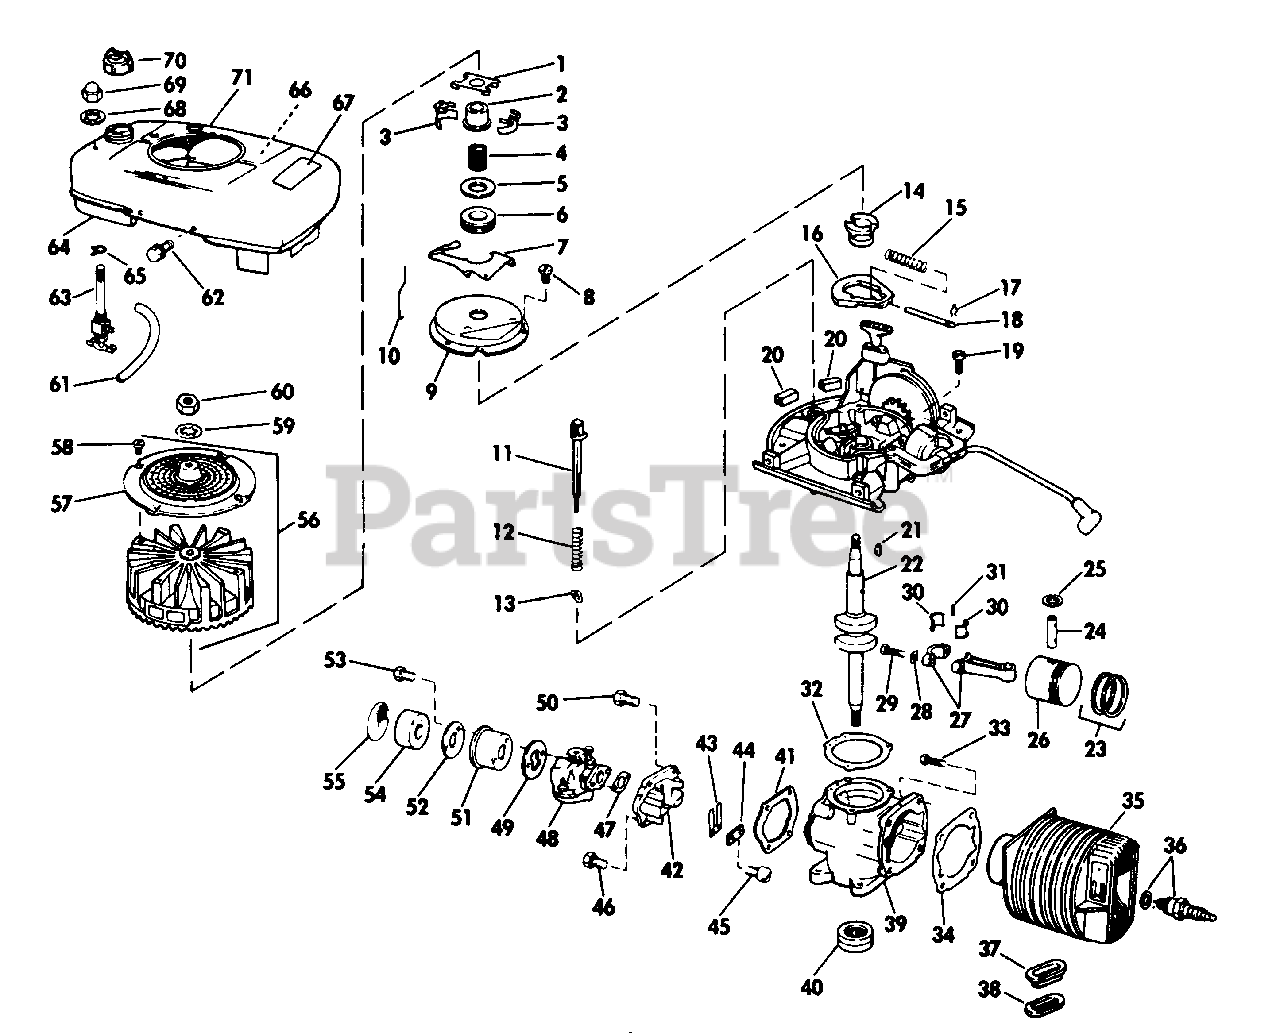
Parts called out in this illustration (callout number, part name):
1	Yoke-Governor
2	Collar-Governor
3	Weight-Governor
4	Spring-Governor
5	Thrust Washer
6	Collar-Thrust
7	Lever-Governor
8	Screw-Attaching Dust Cover
9	Dust Cover
10	Rod-Governor
11	Bar-Shut-Off and Primer
12	Spring-Shut-Off Switch
13	Blade-Switch
14	Cam-Spark Advance
15	Spring-Spark Advance
16	Flyweight-Spark Advance
17	Retainer-Spring
18	Pin-Spark Advance
19	Screw-Arm. Plate to Crankcase
20	Pad-Rubber. Arm. Plate
21	Key-Crankshaft
22	Crankshaft
23	Ring Set (2 Rings)
24	Wrist Pin
25	Retaining Ring-Wrist Pin
27	Connecting Rod Assy.
28	Lockplate
30	Liners-Connecting Rod
31	Needle Set
32	Gasket-Crkc. to Arm. Pl. .005 in.
32	Gasket-Crkc. to Arm. Pl. .010 in.
33	Screw-Machine, Cyl. to Crkc.
34	Gasket-Cyl. to Crankcase
35	Cylinder and Sleeve Assy.
36	Spark Plug and Gasket
37	Sleeve-Exhaust Gasket
38	Gasket-Exhaust
39	Crankcase and Seal Assy.
40	Oil Seal
41	Gasket-Reed Plate
42	Reed Plate Assembly
44	Plate-Back-Up
45	Machine
46	Scr.-Reed Pl. to Crkc.
47	Gasket-Carburetor
48	Carburetor Assembly
50	Scr.-Reed Pl. to Crkc.
51	Cup-Air Filter
52	Plate Back-Up
53	Screw-Filter to Carburetor
54	Element-.Air Filter
55	Screen-Air Filter
56	Flywheel and Screen Assy.
57	Screen and Cup
59	Lockwasher-Flywheel
60	Nut-Flywheel
61	Gas Line
62	Screw-Shroud to Armature Plate
63	Shut-Off Valve
64	Gas Tank Assy.
66	Decal-lawn
67	Decal-Instruction
68	Lockwasher
71	Shroud and Shield Assy.
